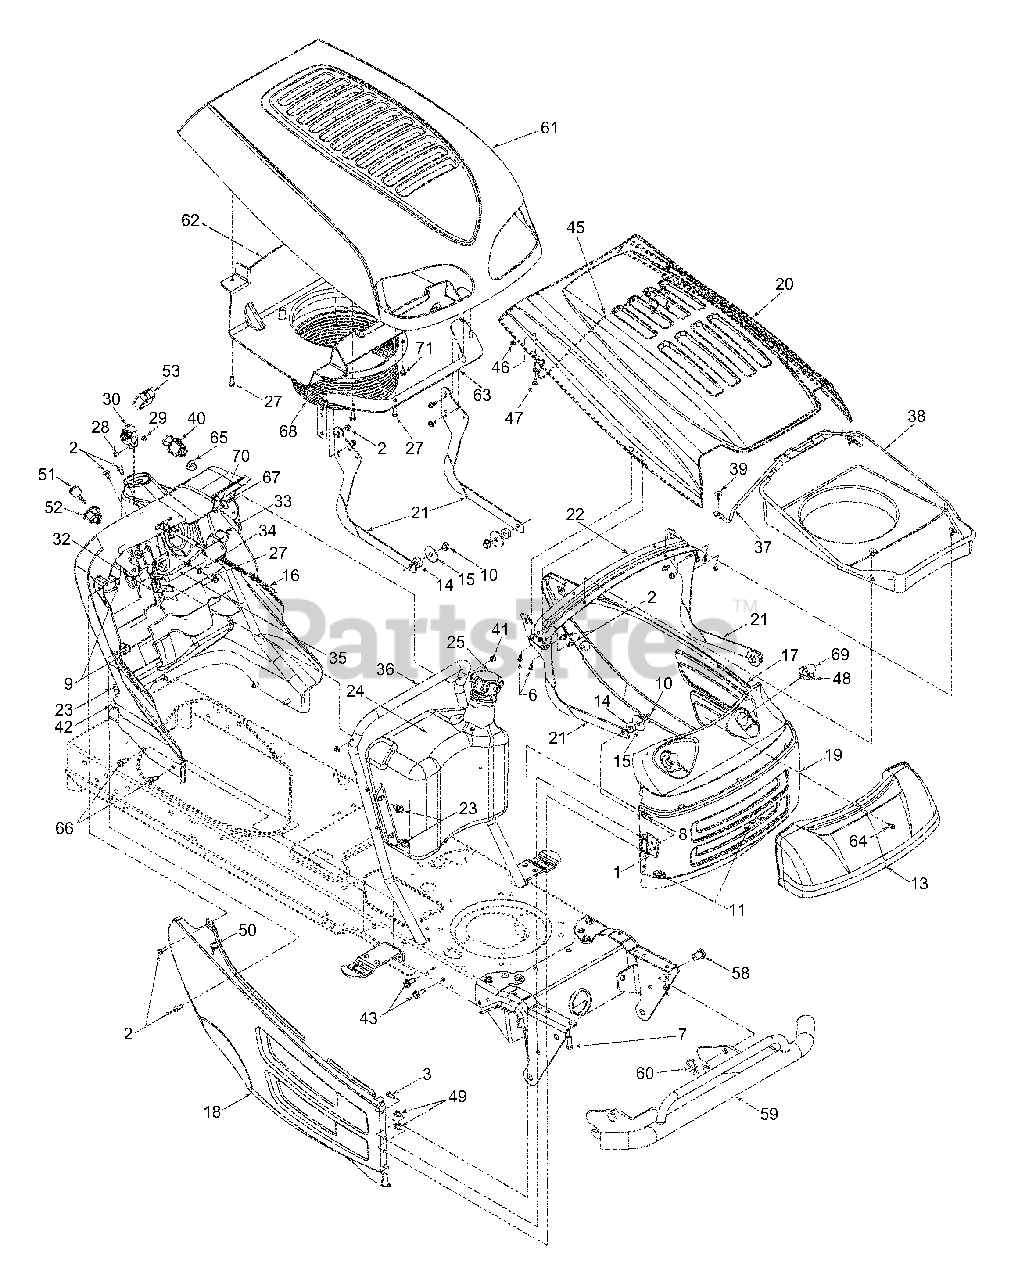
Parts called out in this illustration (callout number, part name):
2	Self-tapping Screw, 1/4-20 x.5
3	Hex Cap Screw, 1/4-20 x.62
4	Phillips Pan Screw, 1/4-20 x.75
6	Screw, #10-16 x.5
7	Hex Cap Screw, 5/16-18 x 1.0
8	Hex Sems Nut, 1/4-20
9	U-type Speed Nut, 1/4-20
10	Flange Lock Nut, 3/8-16
11	U-nut, 5/16-18
13	Headlight Lens (8-style)
14	Rubber Washer,.87 x.33
15	Flat Washer,.406 x 1.5 x 11GA
16	Choke Knob/Cable (Models with any B&S Twin)
24	Fuel Tank, Three Gallon
25	Fuel Cap (Fits Either Tank)
26	Self-tapping Screw, 1/4-20 x 1.25
27	Self-tapping Screw, 1/4-15 x.75
28	Truss Phillips Screw, #8-32 x.375
29	Hex Nut, #8-32
30	Throttle Control Knob
31	Dash Panel (Models w/ Electric PTO)
32	Cruise Control Lever
33	Parking Brake Lever
34	Flat Washer, 9/32 x 1/2 x 1/16
35	Brake/Cruise Pivot Rod
38	Hood Plenum (Models with B&S OHV V-Twin)
39	Ratchet Clip
40	Electric PTO Switch
41	Hex Flange Lock Nut, 1/4-20
42	Flat Washer,.349 x 1.0 x.063
43	Screw, 5/16-18 x.875 (Grade 5)
45	Hood Latch
46	Hex Sems Nut, #10-32
47	Machine Screw, #10-24
48	Headlight Socket
49	Hex Index Washer Screw, 1/4-14 x.0625
50	Rubber Bumper
51	Ignition Key w/ plastic cover
52	Ignition Switch
53	Systems Indicator Monitor w/ Hour Meter
58	Clevis Pin,.50 x.78
59	Bumper Assembly
60	Internal Cotter Pin
61	Hood, Red (7-Style)
62	Hood Plenum
65	Choke Plug
66	Screw, 5/16-18 x.75
67	Bell Washer,.265 x.75 x.062
68	Intake Bellow (Intek Single & kohler)
69	Lamp
70	Self-tapping Screw, 1/4-20 x.75
71	Self-tapping Screw, 1/4-20 x.50
